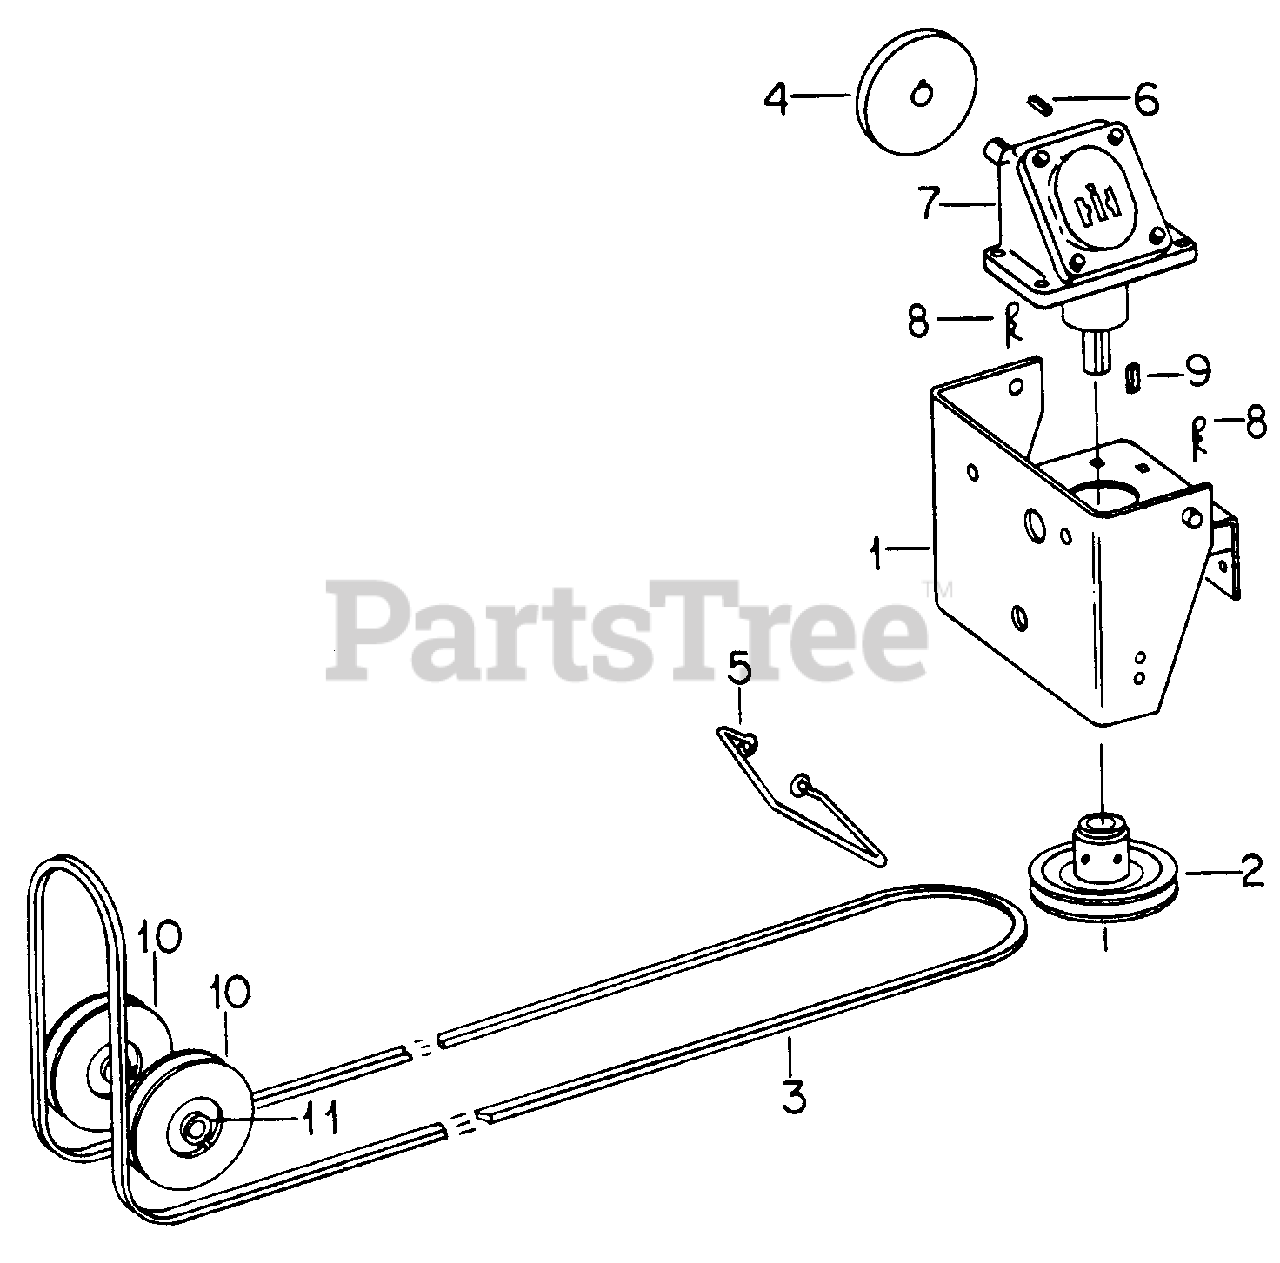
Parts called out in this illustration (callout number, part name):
1	Mounting Assy, Gear Box
2	Pulley w/Set Screws
3	Belt, PTO Drive -Tractor Serial No. 400,000 & below
4	Pulley w/Set Screws
5	Guide, Belt -Hydro Transmission
6	Key, 3/16 X 1-1/4 Sq Parallel
7	Box Assy Gear -90 Degree-
8	Pin, Quick Attachable Cot
9	Key, 3/16 X 2 Sq Parallel
10	Pulley, Drive Belt Idler
11	Bearing Assy, Idler Pulley
